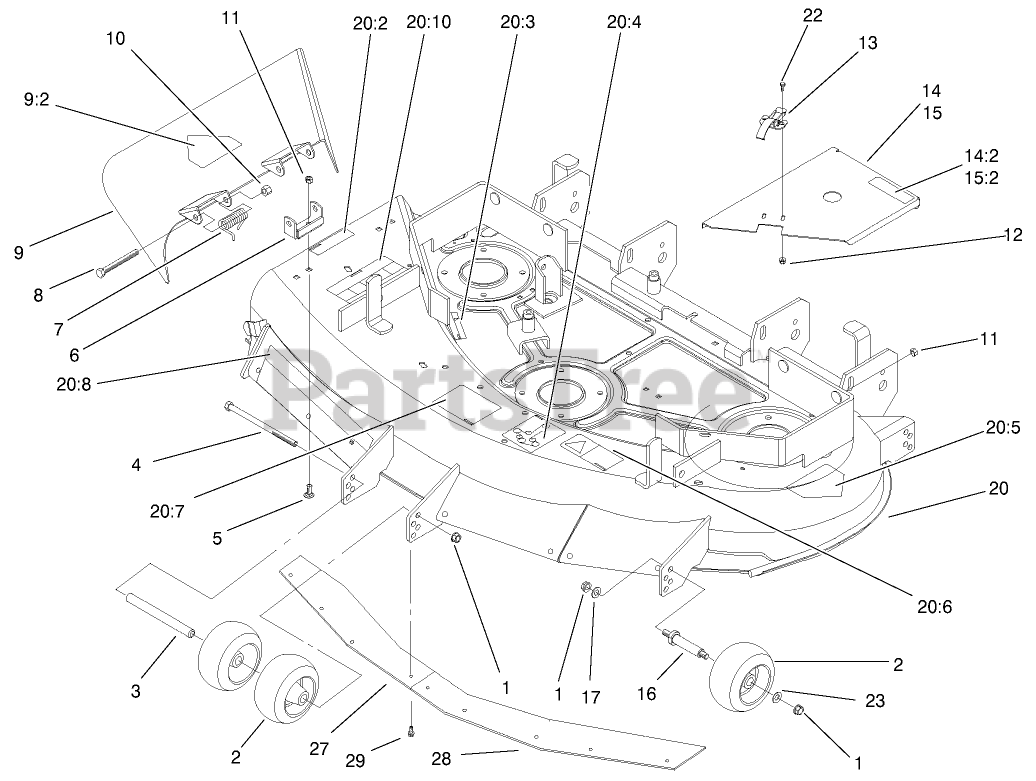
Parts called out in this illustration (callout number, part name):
1	NUT-HHF, WHIZ
2	WHEEL-GAGE
3	SPACER-WHEEL
4	SCREW-HH
5	SCREW-CARR
6	BRACKET-PIVOT
7	SPRING
8	SCREW-HH
9	CHUTE-DISCHARGE
9:2	DECAL-DANGER
10	NUT-HEX
11	NUT-LOCK, CONE
12	NUT-LOCK, FLANGE
13	CLAMP-SLOTTED
14	LH COVER ASM
14:2	DECAL-DANGER
15	RH COVER ASM
15:2	DECAL-DANGER
16	SPACER
17	Washer
20	44" Deck ASM
20:2	DECAL-DANGER
20:3	DECAL-COVER, MISSING
20:4	DECAL-ROUTING, BELT
20:5	DECAL-DANGER
20:6	DECAL-TORQUE, BLADE BOLT
20:7	DECAL-WHEEL, GAGE
20:8	DECAL
20:10	DECAL-DANGER, THROWN OBJECT
22	SCREW-HWH
23	Washer
27	PLATE-BLOWOUT, RH
28	PLATE-BLOWOUT, LH
29	SCREW
